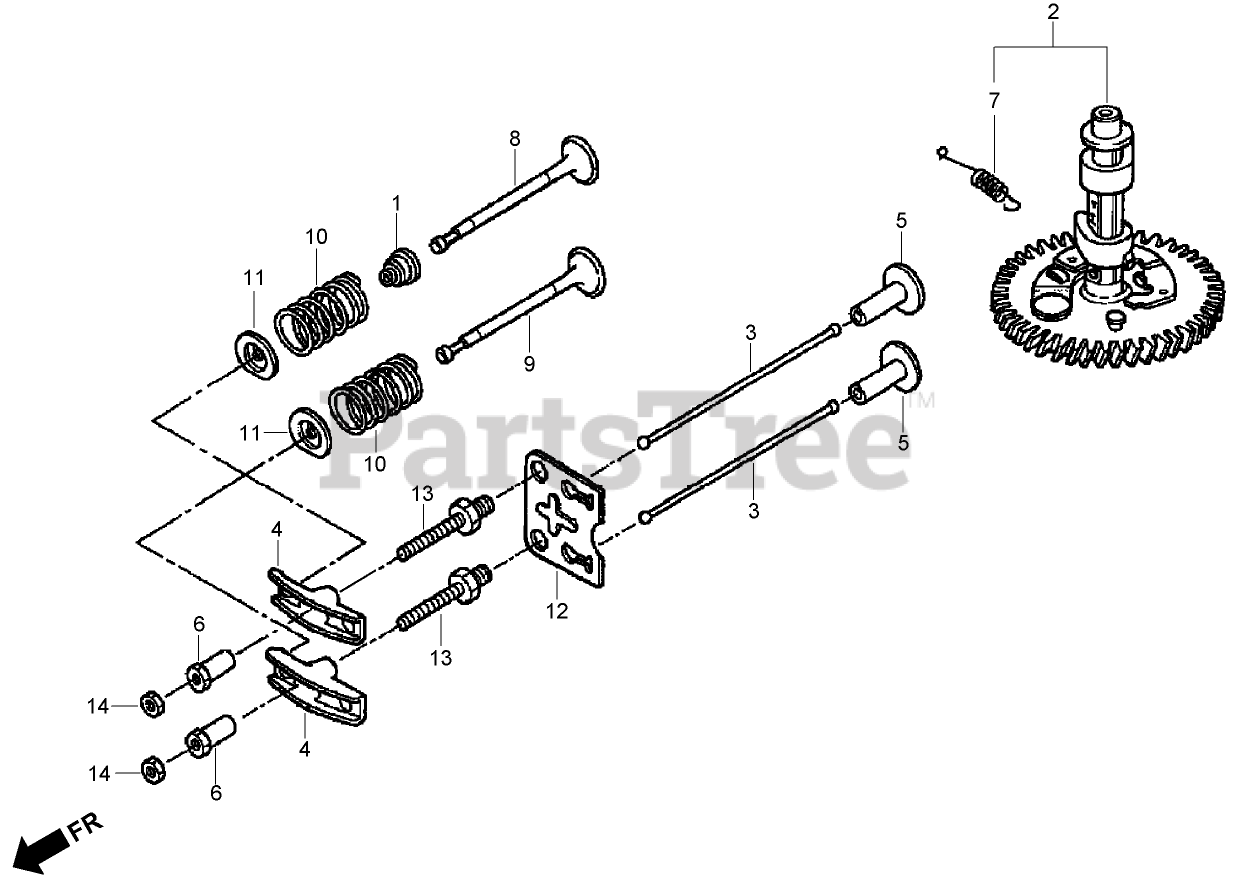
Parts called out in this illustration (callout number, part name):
1	SEAL-STEM, VALVE
2	CAMSHAFT ASM
3	ROD-PUSH
4	ARM-ROCKER, VALVE
5	Lifter-Valve
6	PIVOT-ARM, ROCKER
7	SPRING-RETURN, WEIGHT
8	VALVE-INTAKE
9	VALVE-EXHAUST
10	Spring-Valve
11	RETAINER-SPRING, VALVE (INTAKE)
12	Plate-GUIDE, Push Rod
13	BOLT-PIVOT (8 mm)
14	NUT-ADJUSTING, PIVOT
